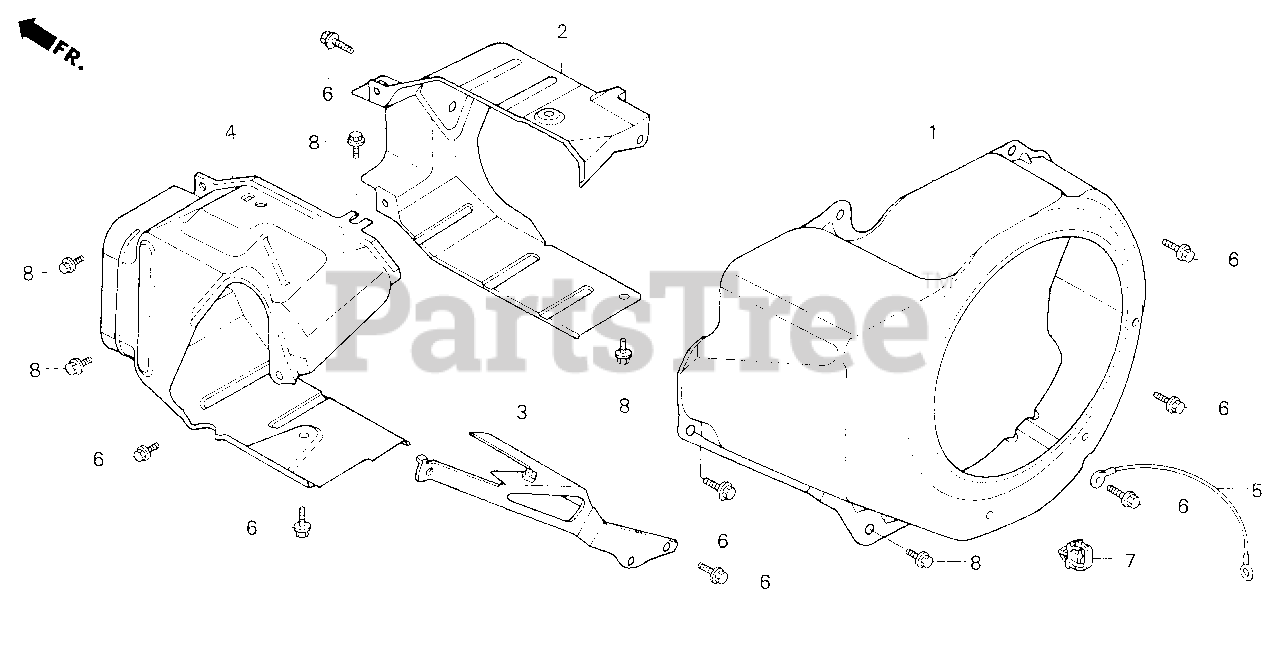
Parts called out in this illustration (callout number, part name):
1	COVER, FAN
2	SHROUD, CYLINDER
3	STAY, SHROUD
4	SHROUD, HEAD
5	CABLE ASSY., BONDING
6	BOLT, FLANGE (6X12) (CT200)
7	CLIP, WIRE HARNESS (BLACK)
8	BOLT, FLANGE (6X8)
